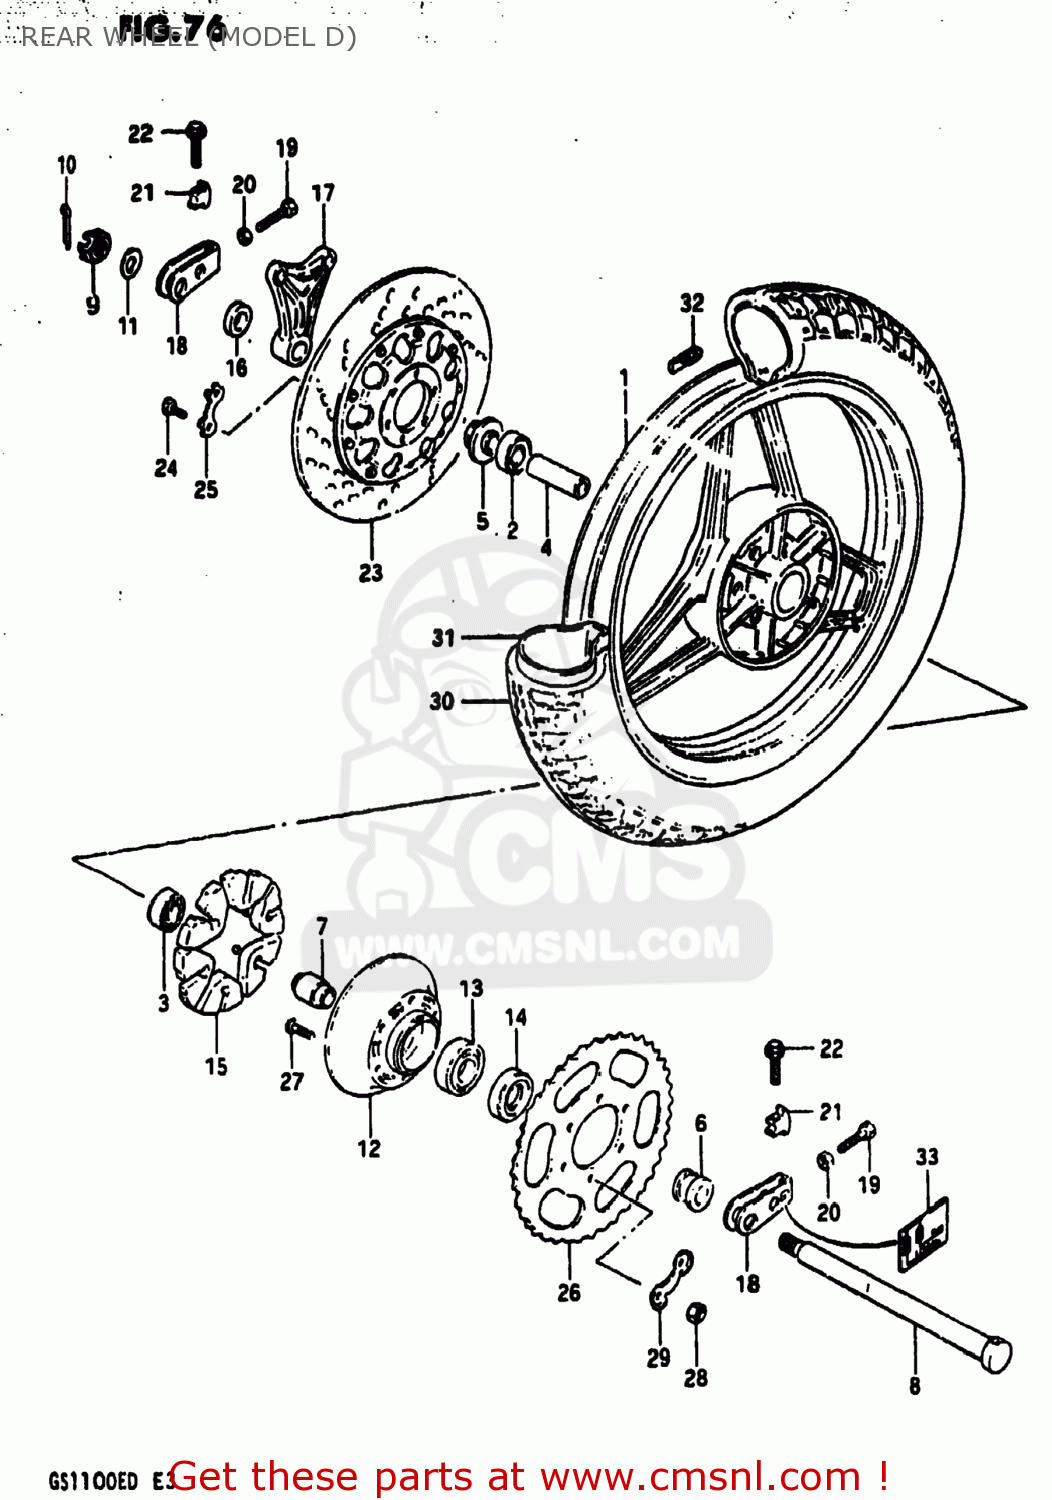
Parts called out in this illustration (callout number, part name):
1	CASTING WHEEL,REAR 2.50
2	BEARING WHEEL REAR(20X47X14)
3	BEARING, LH
4	SPACER(20.5X28X88)
5	SPACER,REAR AXLE
6	SPACER(20X33X28.3)
7	SPACER,REAR HUB BEARING
8	AXLE,REAR
9	NUT 18MM
10	PIN,COTTER
11	WASHER(19X34X4)
12	DRUM,REAR SPROCKET MOUNT
13	BEARING
14	SEAL,OIL(33X62X7)
15	ABSORBER,REAR HUB SHOCK
16	SPACER(20X38X12)
17	BRACKET,RR,CALIPER
18	ADJUSTER,CHAIN
19	BOLT 8X35
20	NUT
21	SUPPORTER,CHAIN ADJUST
22	BOLT
23	DISC,RR BRAKE
24	BOLT(8X30)
25	WASHER
26	SPROCKET,REAR
27	BOLT
28	NUT
29	WASHER
30	TIRE
31	TUBE ASSEMBLY,WHEEL,INNER
32	BALANCER,WHEEL
33	LABEL,CHAIN WEAR INDICATOR
